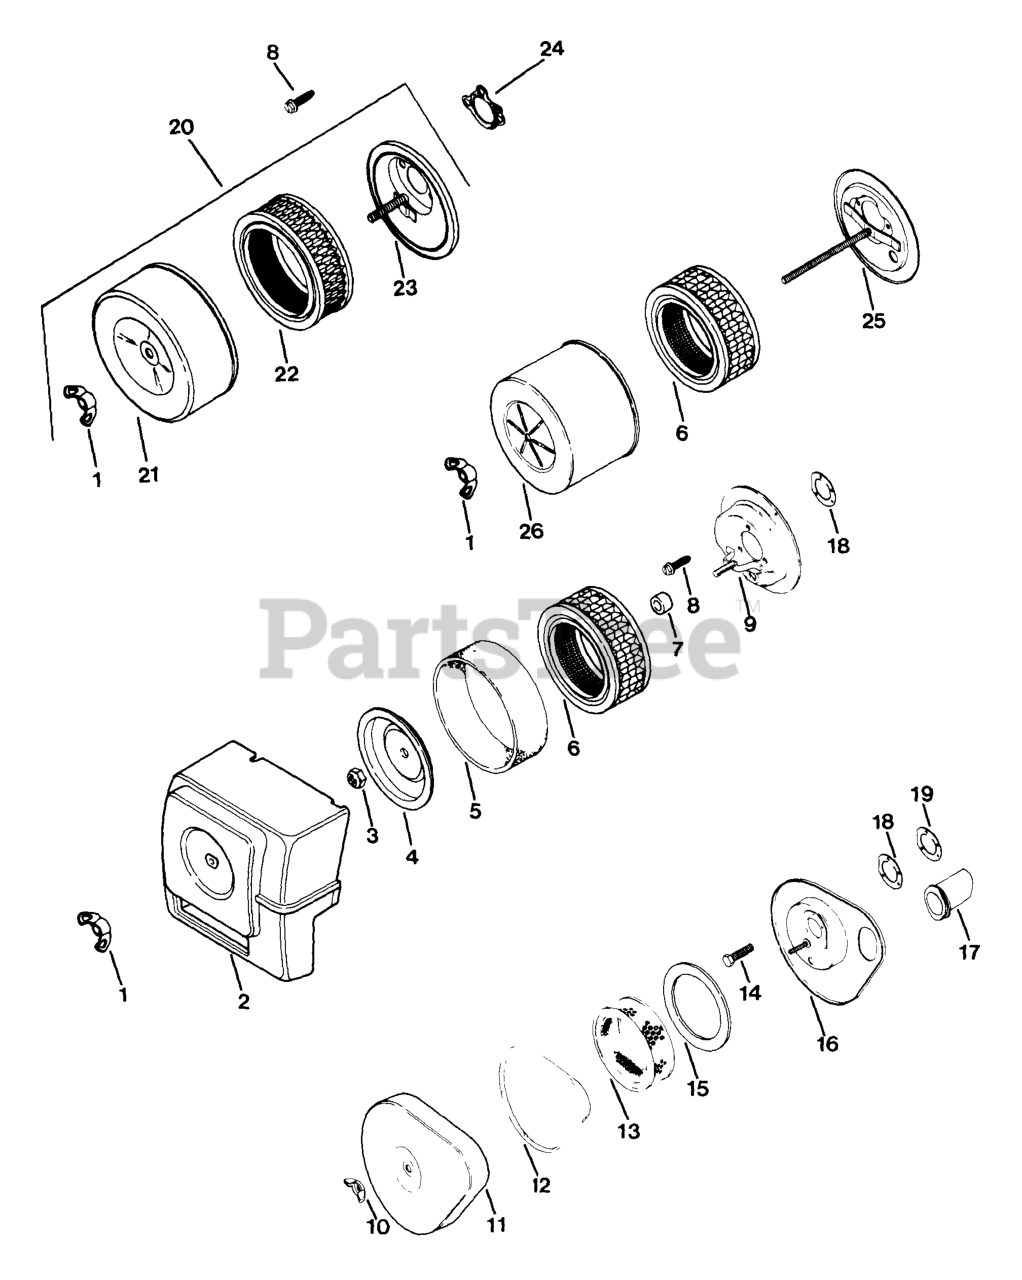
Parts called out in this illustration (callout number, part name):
10	NUT, WING 1/4-20 USE 25 100 15-S
12	SEAL-(#DSC)
14	SCREW, WSH HD TAP #10-32X15/16"
16	BASE - DISCONTINUED
18	GASKET, AIR CLEANER
19	SPACER-DISCONTINUED
